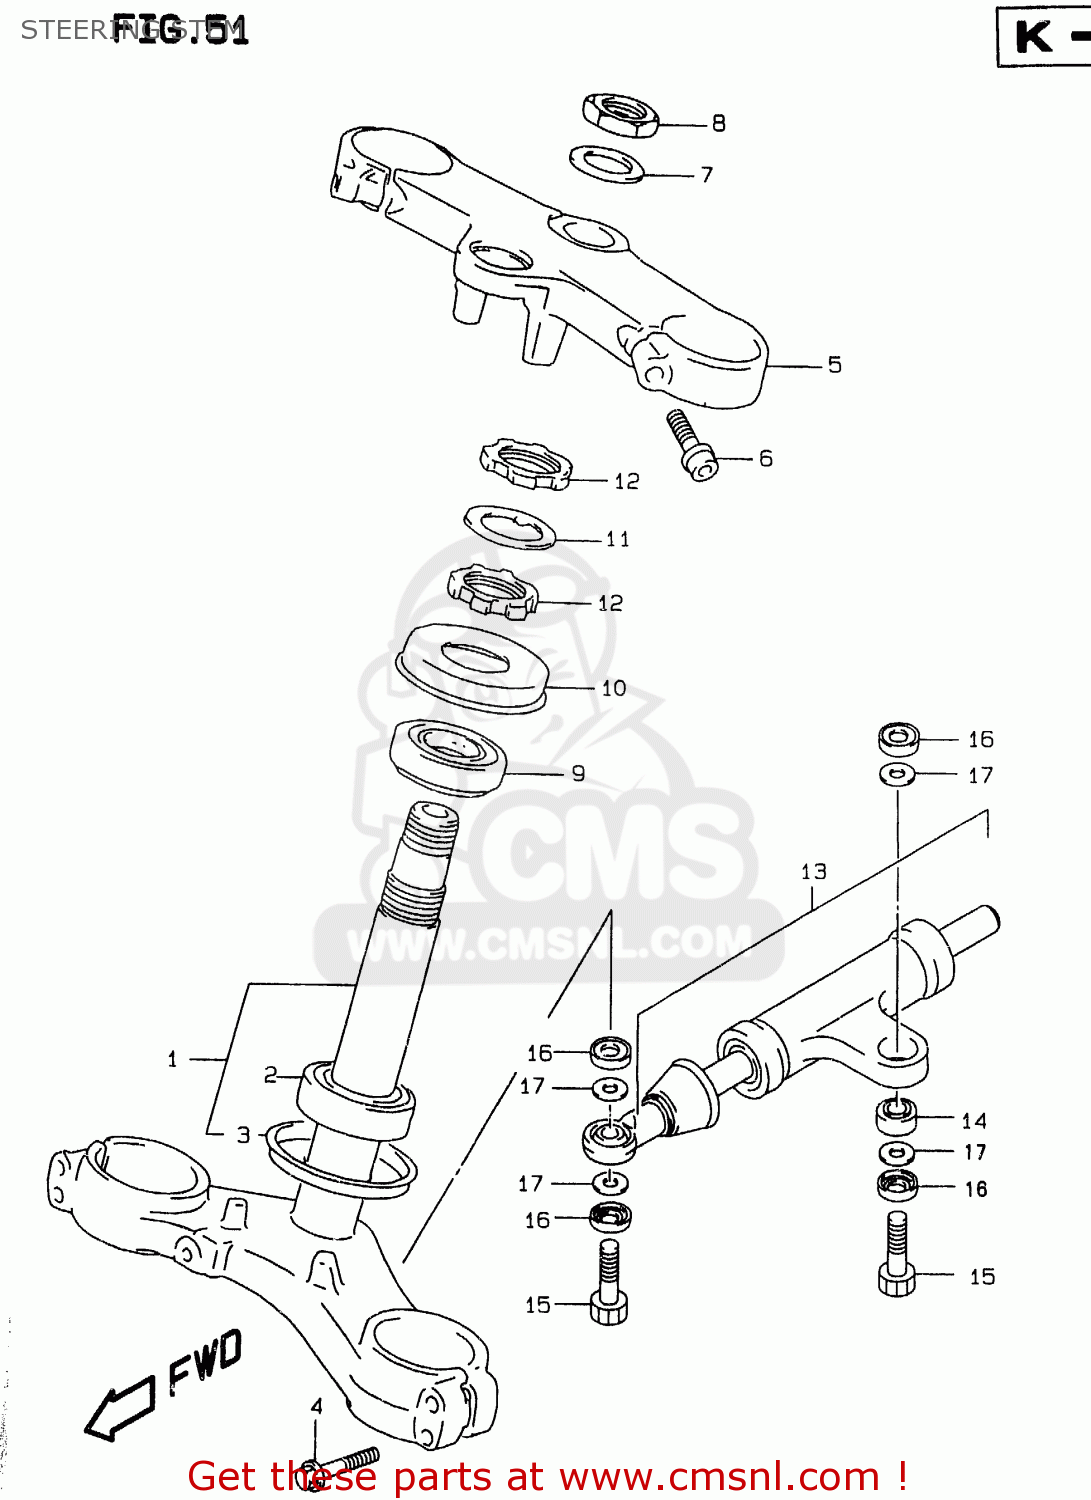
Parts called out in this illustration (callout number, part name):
1	STEM,STEERING
2	BEARING(30X55X17)
3	SEAL,STEERING LWR
4	BOLT
5	HEAD,STEERING STEM
6	BOLT
7	WASHER
8	NUT,STEM HEAD
9	BEARING(30X55X17)
10	SEAL,STEERING UPR DUST
11	WASHER,STEERING STEM
12	NUT,STEERING STEM
13	DAMPER ASSY,STEERING
14	BEARING(8X17.5X11)
15	BOLT
16	17
17	SHIM(8X12X0.8)
